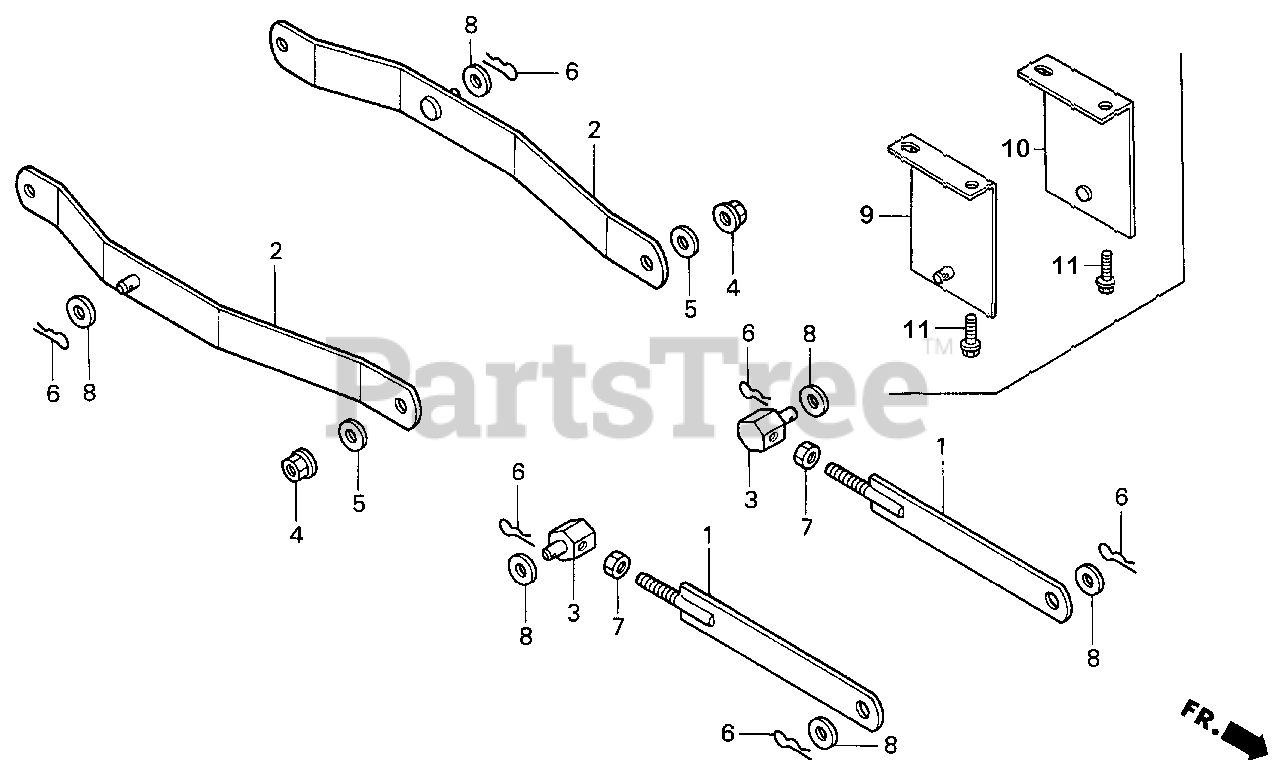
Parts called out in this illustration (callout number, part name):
9	BRACKET, R. ROLLER
10	BRACKET, L. ROLLER
11	BOLT, FLANGE (10X20)
